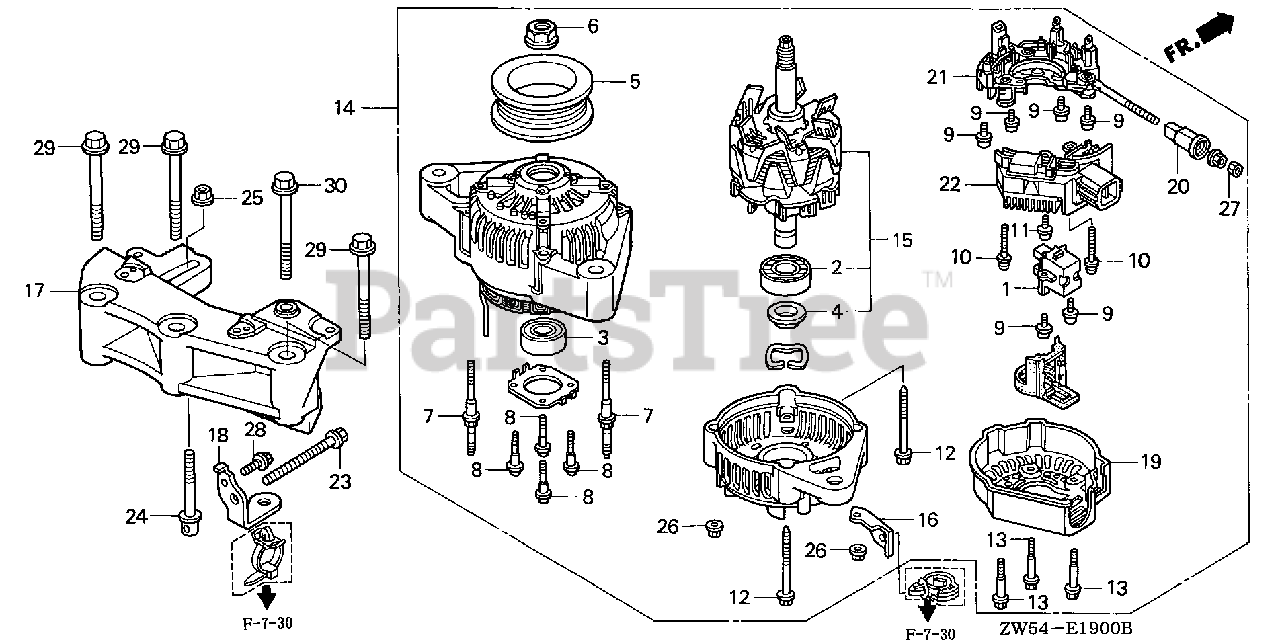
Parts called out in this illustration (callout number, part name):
1	HOLDER ASSY., BRUSH
2	BEARING, RR.
3	BEARING, FR.
4	COVER, BEARING
6	NUT, PULLEY LOCK
7	BOLT, STUD
9	SCREW-WASHER
10	SCREW-WASHER (4X25)
12	BOLT-WASHER
14	ALTERNATOR ASSY.
15	ROTOR ASSY.
16	BRACKET, HARNESS CLAMP
17	BRACKET, ALTERNATOR
18	STAY, ALTERNATOR
19	END COVER, RR.
20	BUSH, INSULATION
21	RECTIFIER ASSY.
22	RECTIFIER ASSY., REGULATOR
23	BOLT, SPECIAL ADJUSTER
24	BOLT, TENSIONER
25	NUT, FLANGE (8MM)
26	NUT-WASHER (5MM)
27	NUT, HEX. (6MM)
28	BOLT, FLANGE (6X14)
29	BOLT, FLANGE (10X70)
30	BOLT, FLANGE (10X80)
